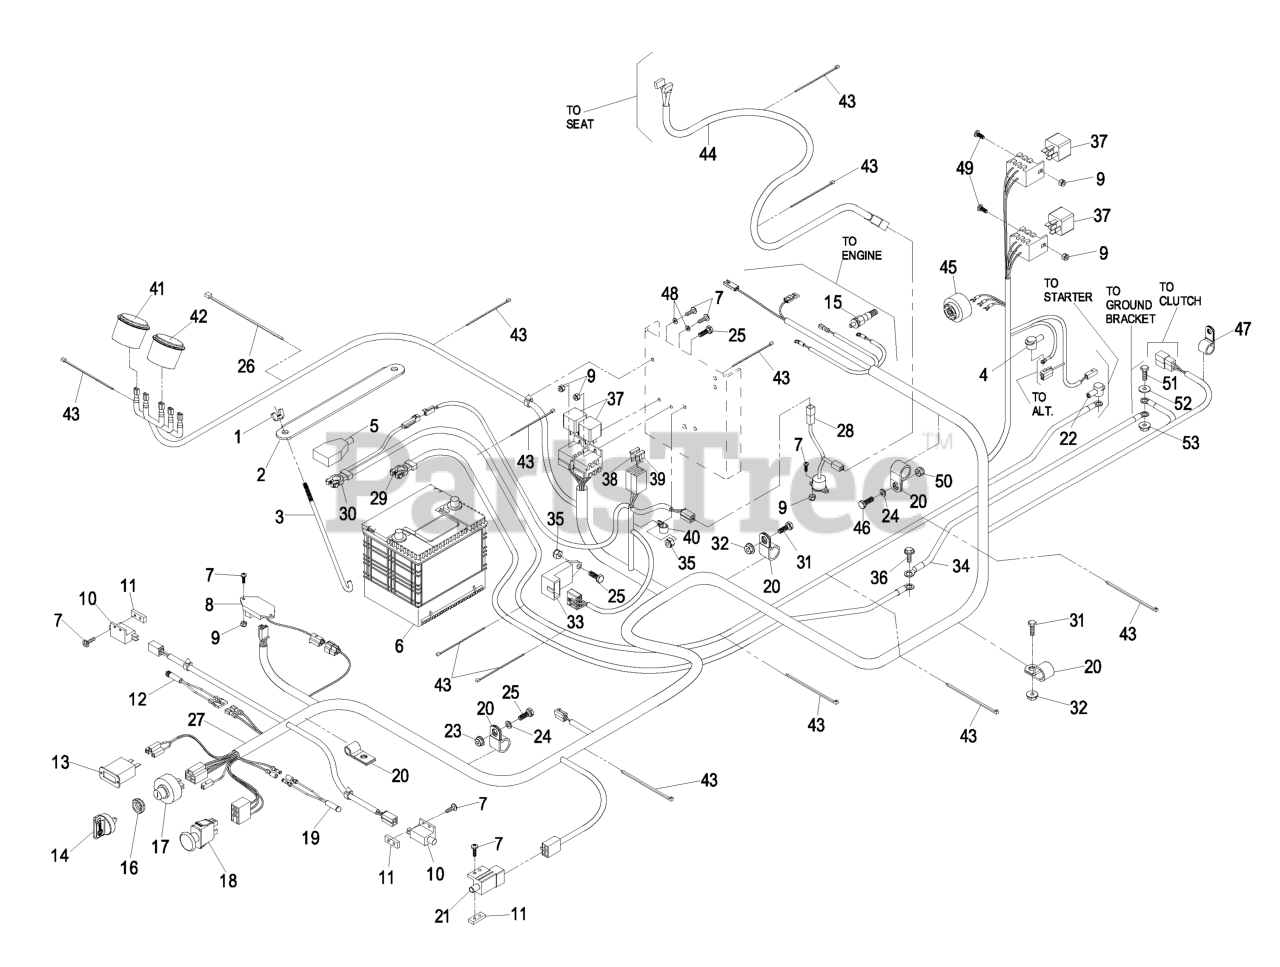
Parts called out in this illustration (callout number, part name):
1	WINGNUT
2	HOLDDOWN-BATTERY
3	BOLT-HOLDDOWN
4	CAP-INSULATOR, RED
5	INSULATOR-TERMINAL, BATTE
6	Battery, 12v SAE Post
7	SCREW-PPH
8	MODULE-DELAY, SEAT
9	NUT-LOCK, NI
10	SWITCH-OPEN, NORMALLY
11	PLATE-TAPPED
12	INDICATOR-LED, RED
13	METER-HOUR
14	KEY-IGNITION
15	SENDER-TEMPERATURE
16	NUT-SWITCH, IGNITION
19	INDICATOR-LED, AMBER
20	CLIP-LOOM
22	INSULATOR-STARTER
24	WASHER-FLAT
25	SCREW-HH
26	TIE-PLASTIC
29	CABLE-BATTERY NEGATIVE
30	CABLE-STARTER
31	SCREW-HH
34	CABLE-ENGINE NEGATIVE
35	NUT-LOCK, NI
36	Screw-HWH 5/16-18 X 3/4 Tf
38	FUSE-BLADE TYPE, 20 AMP
39	FUSE-40 AMP
40	CLIP-LOOM
41	GAUGE-VOLTMETER
42	GAUGE-TEMPERATURE
43	TIE-PLASTIC
44	HARNESS-WIRING, SEAT
45	ALARM-TONE, DUAL
46	SCREW-HH
47	CLIP-LOOM
48	WASHER-FLAT
50	NUT-LOCK
51	SCREW-HH
52	WASHER-FLAT
53	NUT-HHF, WHIZ
